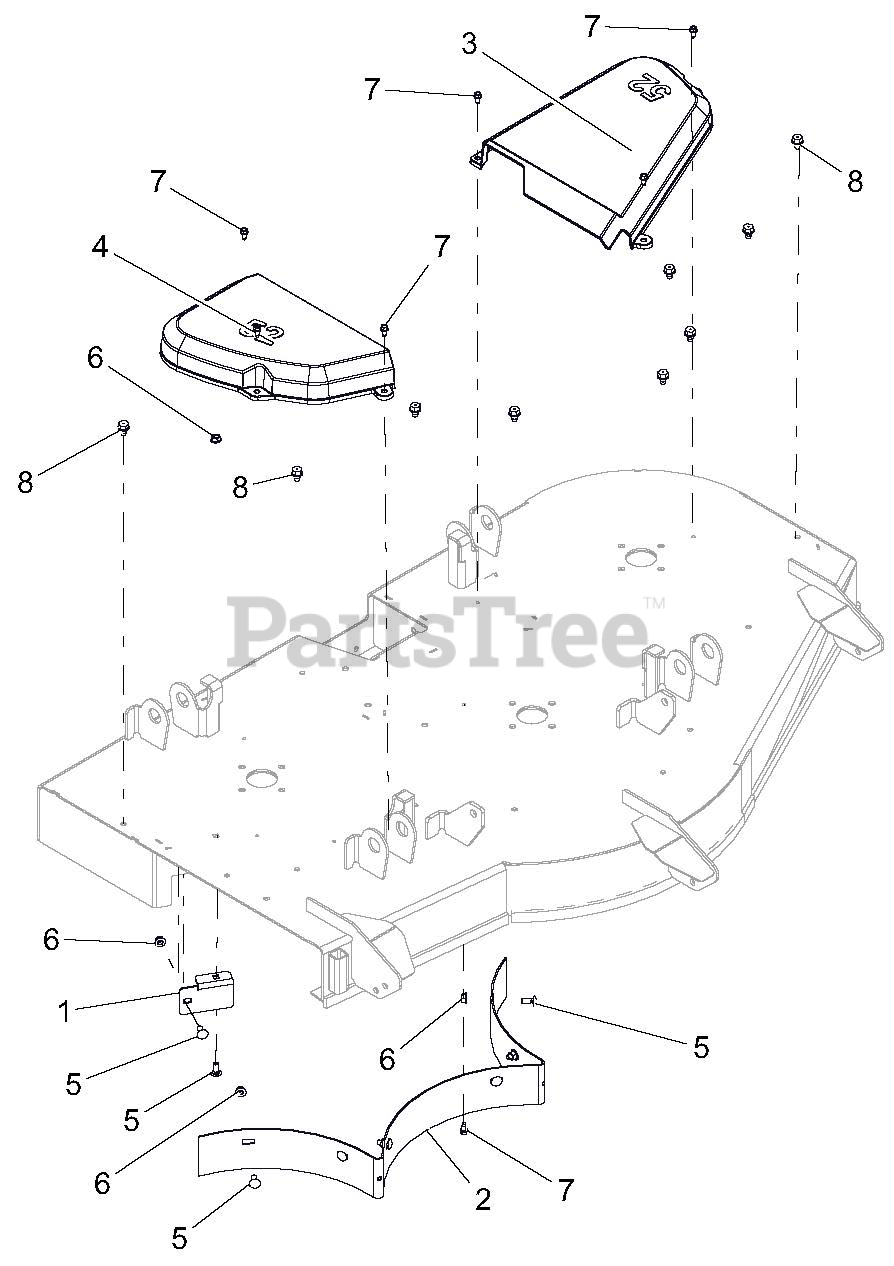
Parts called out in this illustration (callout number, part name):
1	STRIP, DEFLECTOR - 52"
2	BAFFLE, REAR - REMOVABLE 52"
3	COVER, BELT 52" LH
4	COVER, BELT 52" RIGHT
5	@BLT-RDHDSQNK .31-18X.75 G5YZ
6	@NUT-LK-TOP-FLG .31-18 YWZC
7	SCR-TAP .25-20X.50 HWH TR YWZ
8	@SCR-TAP .38-16X.50 HWH TR YWZ
